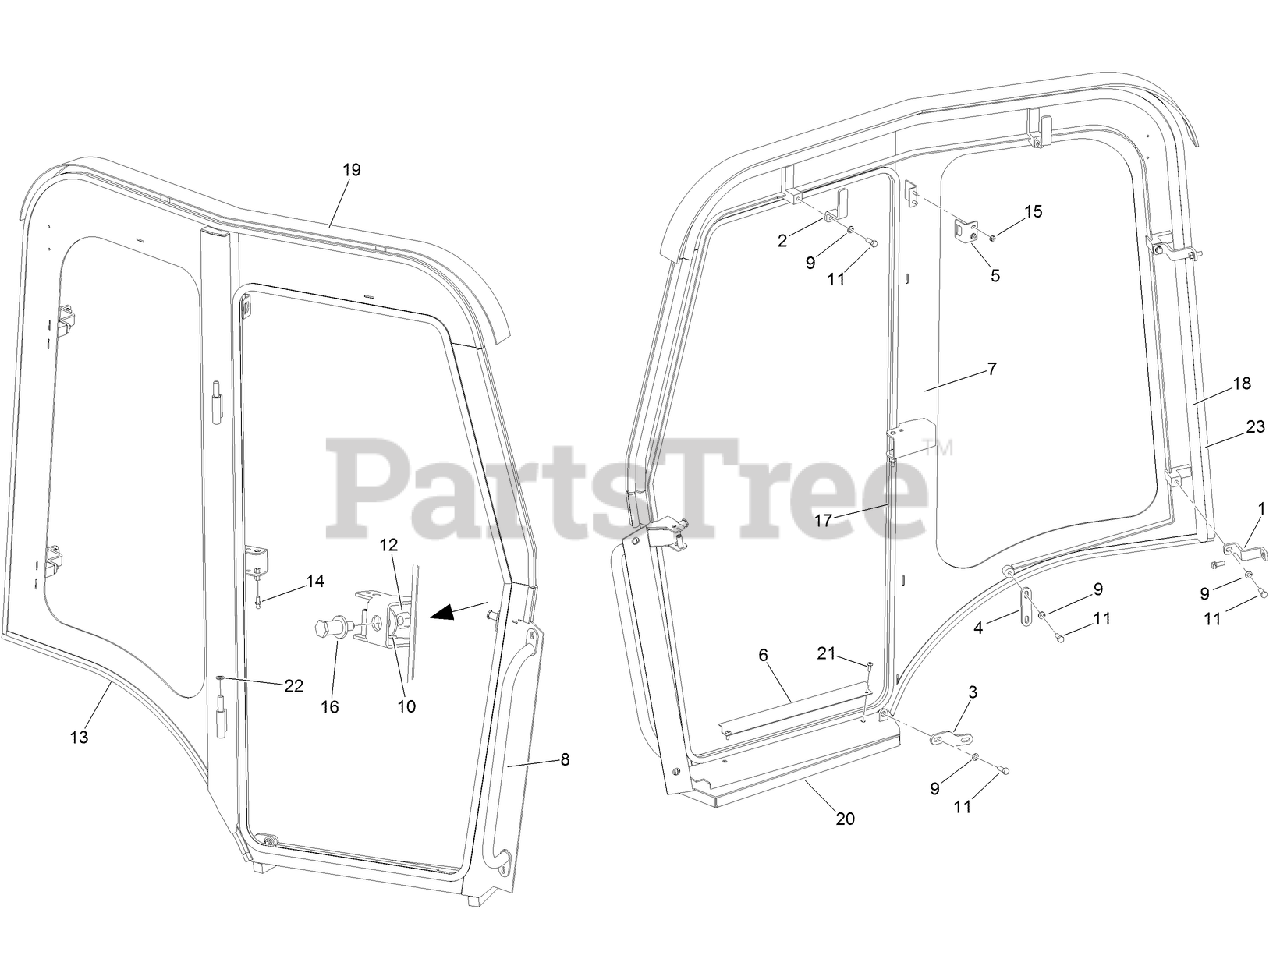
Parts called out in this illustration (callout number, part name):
1	BRACKET-MOUNT, SIDE PANEL
2	BRACKET-MOUNT, SIDE PANEL
3	STRAP-MOUNT, SIDE PANEL
4	STRAP-SIDE PANEL MOUNT
5	COVER-SWITCH, RH
6	BRACKET-SEAL, TRIM
7	SIDE PANEL-RH
8	HANDLE-GRAB
9	WASHER-LOCK
10	WASHER-FLAT
11	BOLT-HHCS
14	STUD-BALL, GAS SPRING
15	NUT-HEX
16	STUD STRIKER ASM
17	SEAL-RUBBER
18	SEAL-RUBBER
19	SEAL-FLAP
20	SEAL-STRIP
21	SCREW-TORX
22	WASHER-HINGE, BRASS
23	SEAL-CLIP ON
